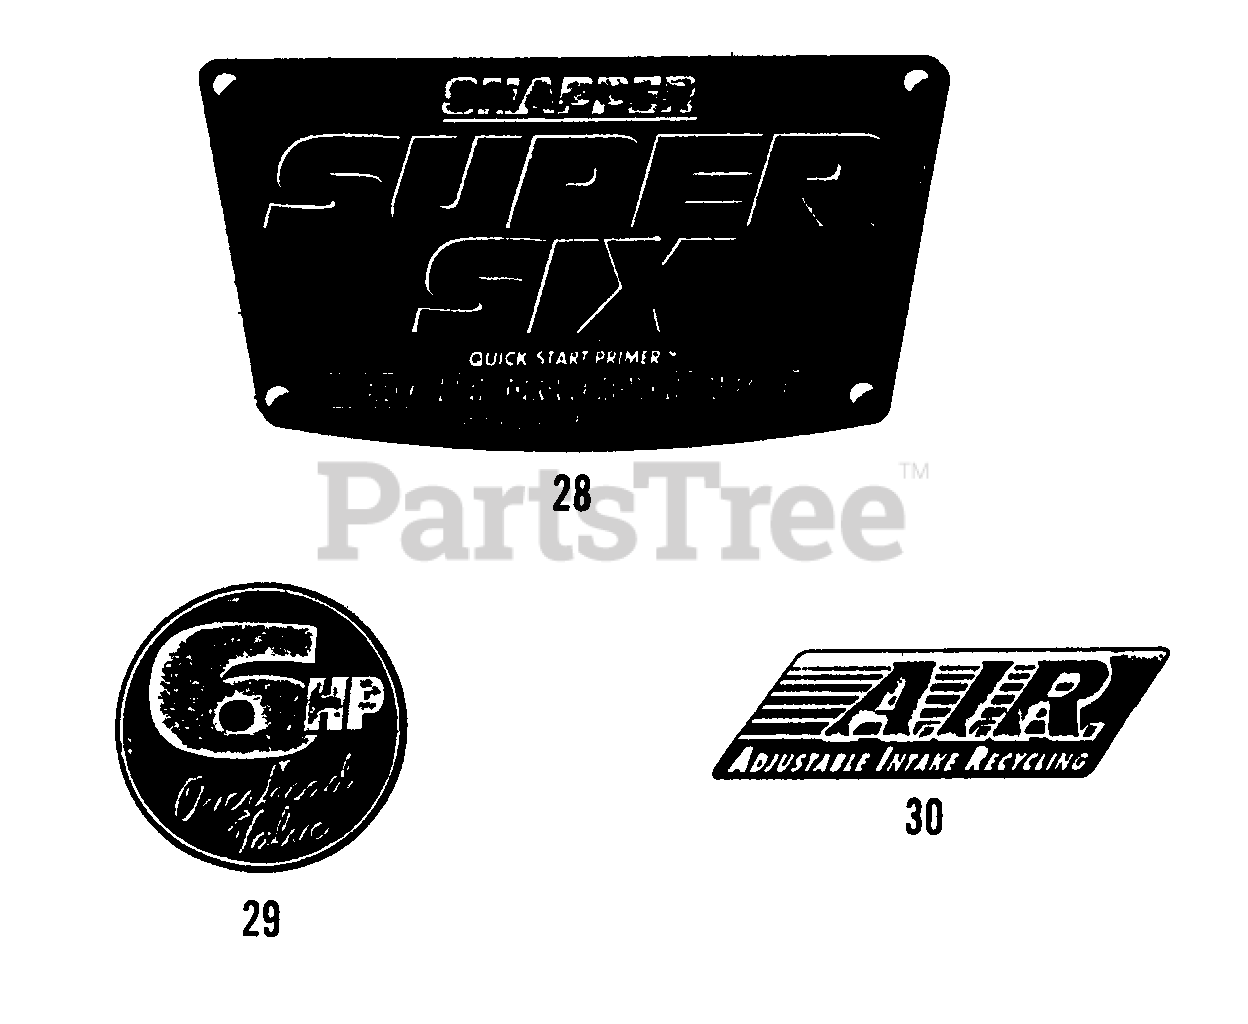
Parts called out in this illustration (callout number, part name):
28	DECAL, Engine - Starter
29	DECAL, Shroud - Engine
30	DECAL, Medallion - Deck
